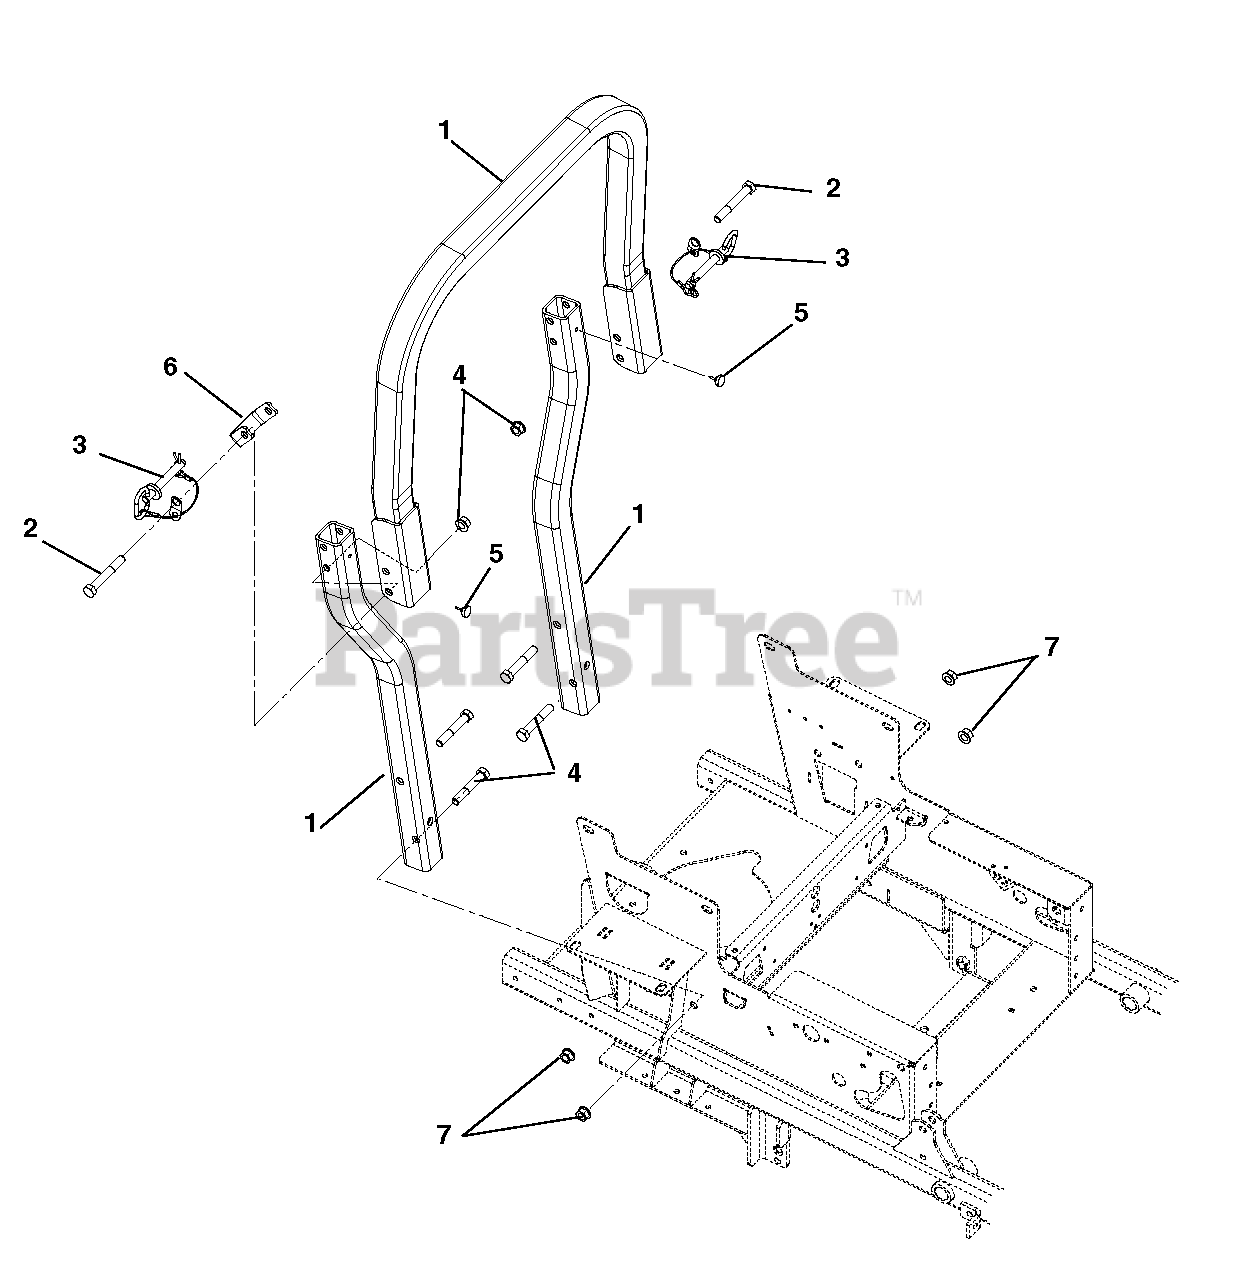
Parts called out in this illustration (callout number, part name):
1	ROPS, PT100 Replacement
2	Bolt, Hex .50-13 x 3.50 Grade 5
3	Assembly, ROPS PIN/LANYARD
4	Nut, Locking-Top-Flange .50-13
5	Bumper, ROPS Rubber
6	Bracket, ROPS Stop, Pro-TURN
7	Bolt, Hex .50-13 x 3.00 Grade 5
